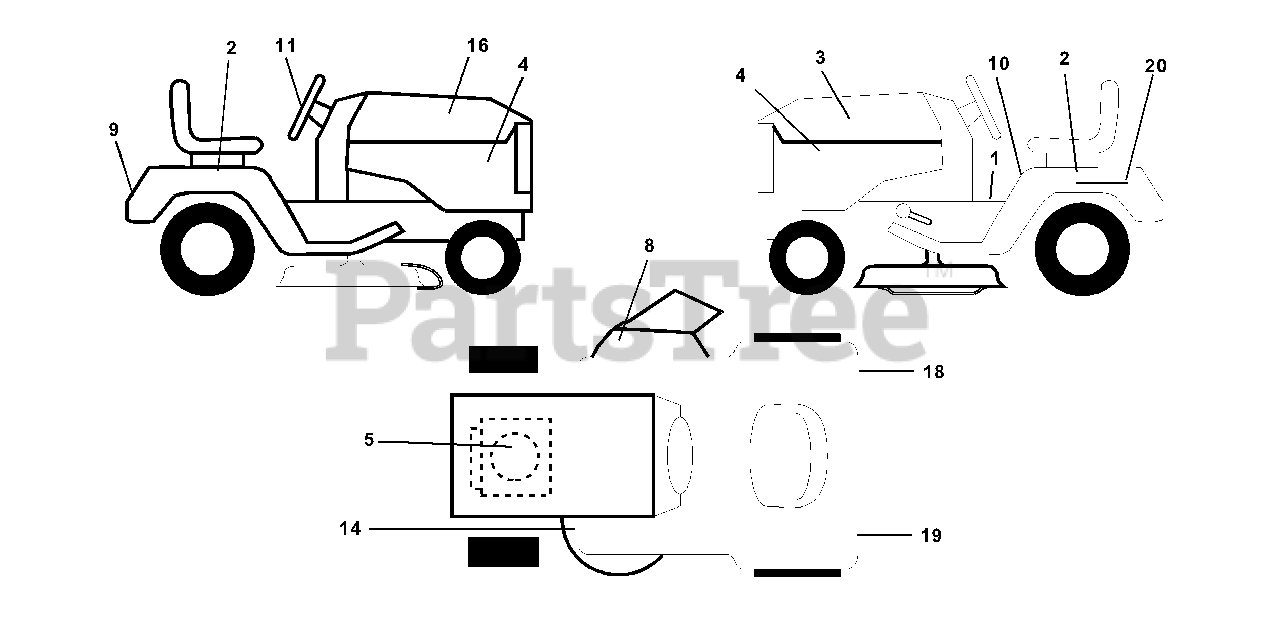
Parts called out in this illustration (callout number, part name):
2	Decal Fender Side Lh
3	Decal Hood LH
4	Decal Side Panel Logo
5	Decal HP Engine
8	Decal Warning Mult-Language
9	Decal Fender Logo
10	Decal Fender Danger E/F
11	Decal Ins Strg Whl
14	Decal V-Belt Schematic
16	Decal Hood Rh
18	Decal Fender Reflector RH
19	Decal Fender Reflector LH
20	Decal Bat Dan/Psn
